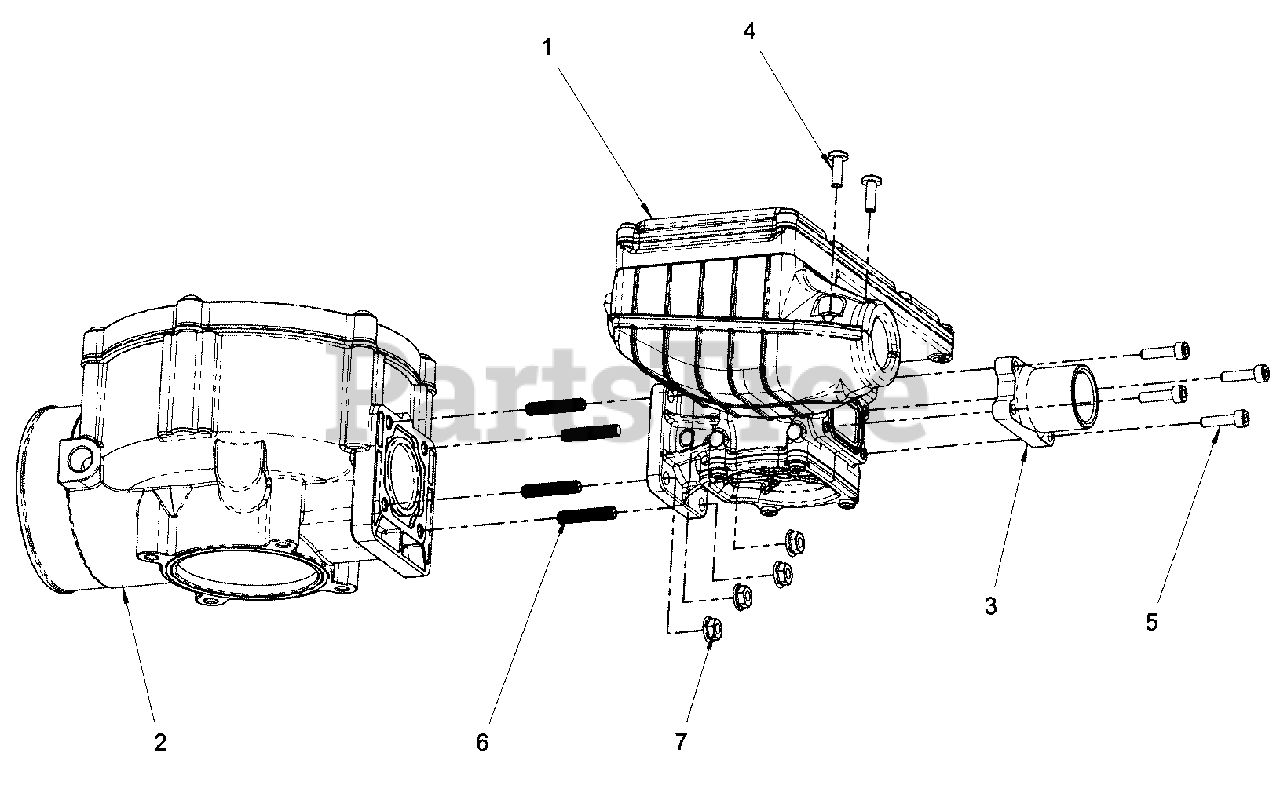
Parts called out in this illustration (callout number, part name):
1	I EPR
2	MIXER
4	SCREW, TAB
5	BOLT
6	STUD
7	NUT
